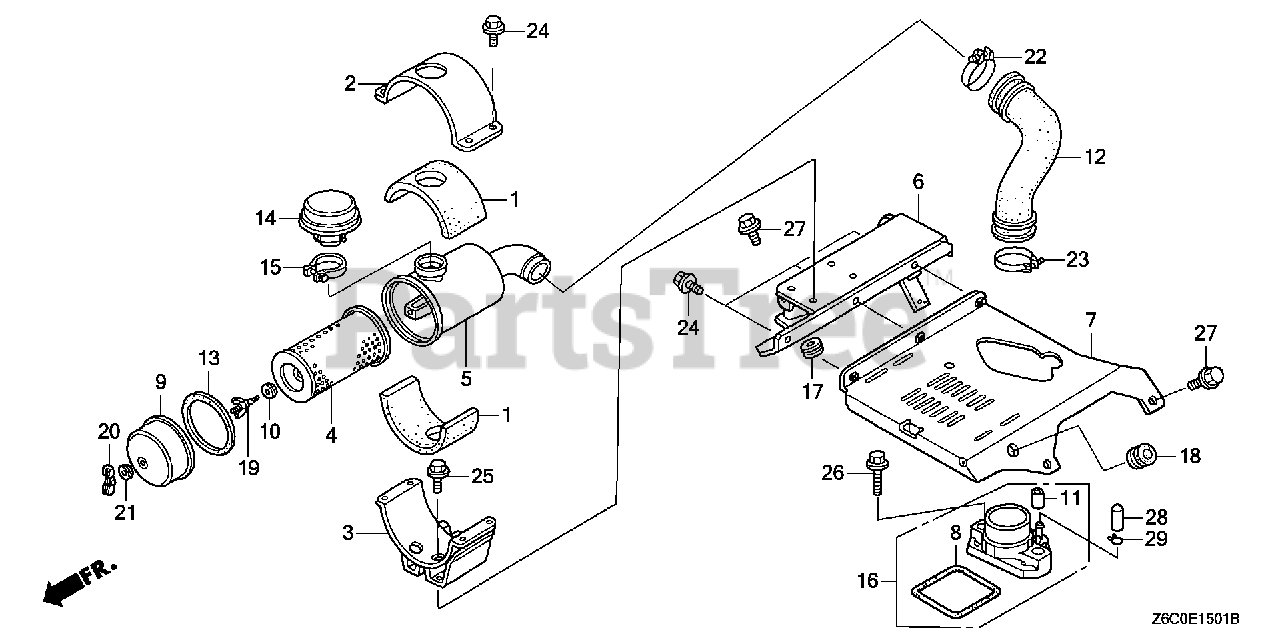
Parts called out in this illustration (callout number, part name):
1	RUBBER, AIR CLEANER HOLDER (UPPER)
2	HOLDER COMP., AIR CLEANER (UPPER)
3	HOLDER, AIR CLEANER (LOWER)
4	ELEMENT, AIR CLEANER
5	HOUSING COMP., AIR CLEANER (SNORKEL)
6	STAY COMP. A, AIR CLEANER (SNORKEL)
7	STAY B, AIR CLEANER (SNORKEL)
8	SEAL, AIR CLEANER HOUSING
9	COVER COMP., AIR CLEANER
10	WASHER, AIR CLEANER
11	COLLAR A, AIR CLEANER
12	TUBE, AIR CLEANER CONNECTING
13	SEAL, AIR CLEANER
14	CAP COMP., IN.
15	CLAMP ASSY.
16	JOINT ASSY., CONNECTING TUBE (B)
17	GROMMET, RESERVE TANK
19	BOLT, AIR CLEANER
20	WINGNUT (6MM)
21	GROMMET, AIR CLEANER
22	BAND, AIR CLEANER CONNECTING TUBE (52)
23	BAND, AIR CLEANER CONNECTING TUBE (58)
24	BOLT, FLANGE (6X12) Use up to Engine SN 1543277.
25	BOLT, FLANGE (6X16) Use from Engine SN 2056820.
26	BOLT, FLANGE (6X28)
27	BOLT, FLANGE (8X20) Use up to Engine SN 1609606.
28	CAP, SEALING
29	CLIP, TUBE (B10)
